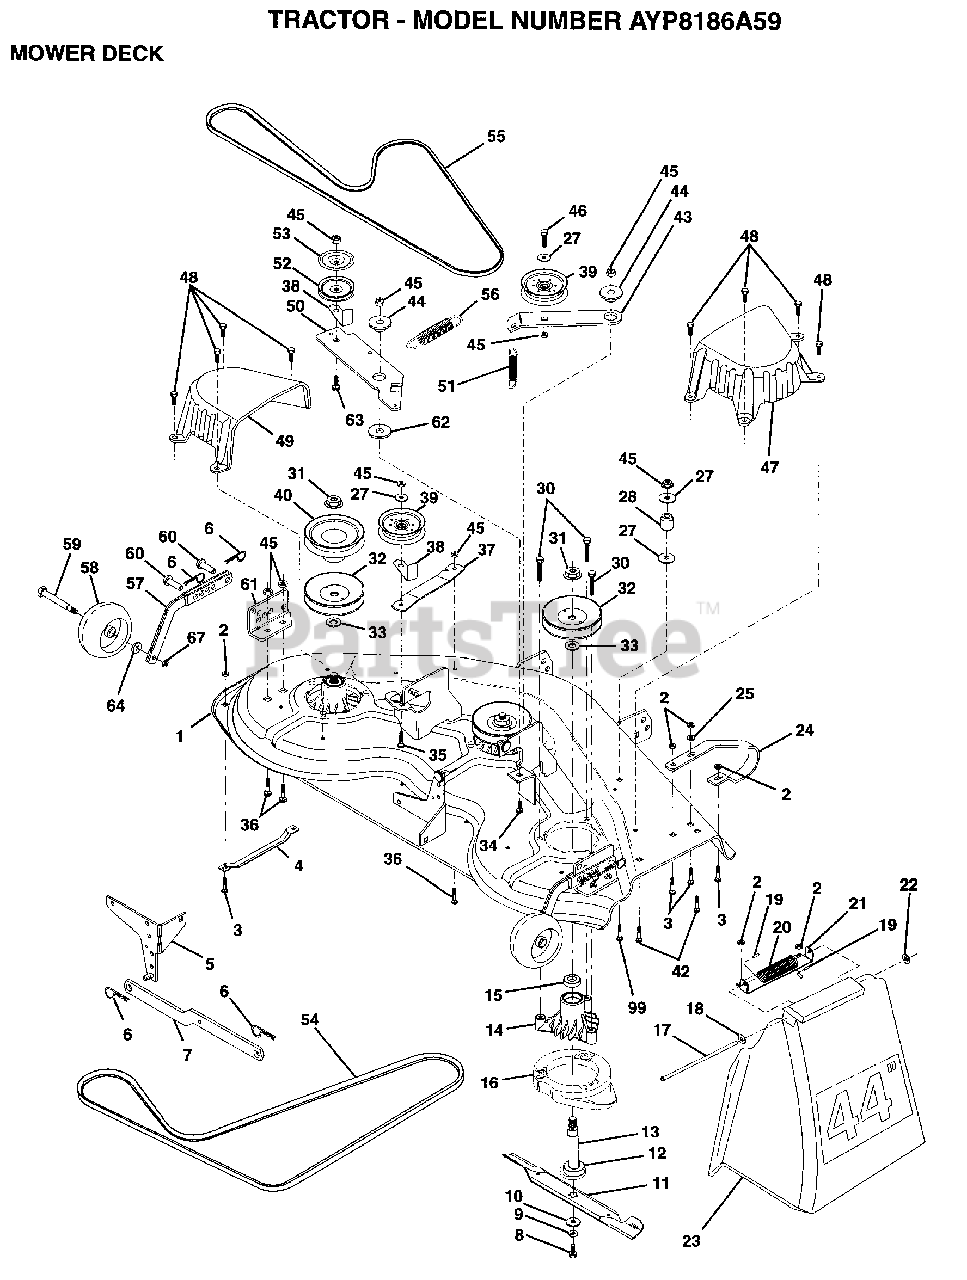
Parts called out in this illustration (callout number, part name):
1	"DECK ASM WELD44"""
4	RUNNER-LH M
5	BRKT.ASM.SW.44/50
8	BLADE BOLT
10	WASHER.HARD.BLADE
11	"BLADE.44"" HIPERF"
12	BEARING.BALL
13	SHAFT.ASM.W/BRNG
14	HOUSING.MAND.44.V
15	BEARING
16	STRIPPER RND MWR
17	ROD-HINGE T
18	WASHER
19	CAP-SLEEVE LT
20	SPRING TORSION
21	BRKT DEFLECTOR
22	NUT PUSH M
23	DEFLECTOR SHIELD
24	RUNNER.RH
25	WASHER M
27	WASHER
33	WASHER
34	BOLT.3/8-14X1.25
35	BOLT
36	BOLT D
37	STIFFENER.ARM.IDL
39	FLAT IDLER PULLEY
40	"PULLEY.DRIVEN.44"""
42	BOLT
43	"ARM.IDLER.SEC.44"""
44	SPACER RETAINER
47	"COVER.MAND.RH.44"""
48	SCREW.1/4-20X5/8
49	COVER.MANDREL.LH
50	ARM.IDLER.PRIMARY
51	"SPRING.SEC.44""VEN"
52	PULLEY.IDLER.VGRO
53	SHIELD.IDLER.44.V
54	V-BELT.PRIM.78.5.
55	BELT-V.88.12.MW
56	SPRING.EXT.DECK.
57	BAR.ASM.GUAGE.WHL
58	WHEEL GAGE DONUT
59	BOLT.SHOULDER
60	PIN.CLEVIS
61	BRACKET.GUAGE.WHL
62	HARDENED WASHER
63	BOLT.3/8-16X1.50
64	WASHER
67	LOCKNUT
99	BOLT
